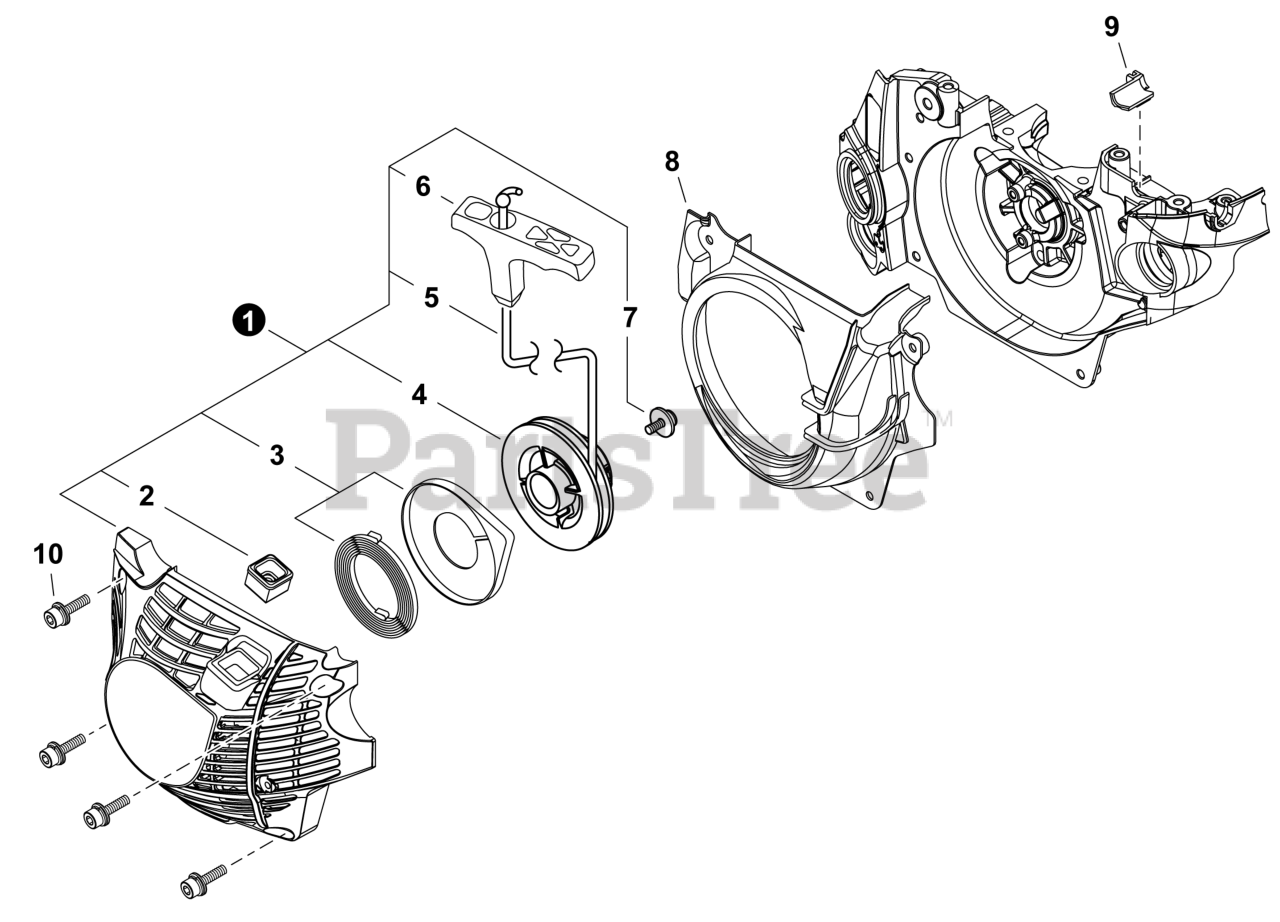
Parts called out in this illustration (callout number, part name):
1	STARTER ASSY, RECOIL
2	GUIDE, ROPE
3	RECOIL SPRING W/CASE
4	REEL, ROPE
5	ROPE, STARTER 4.0x880
6	GRIP, STARTER
7	SCREW 5
8	COVER, FAN
9	GROMMET, NEEDLE
10	BOLT M4x16
